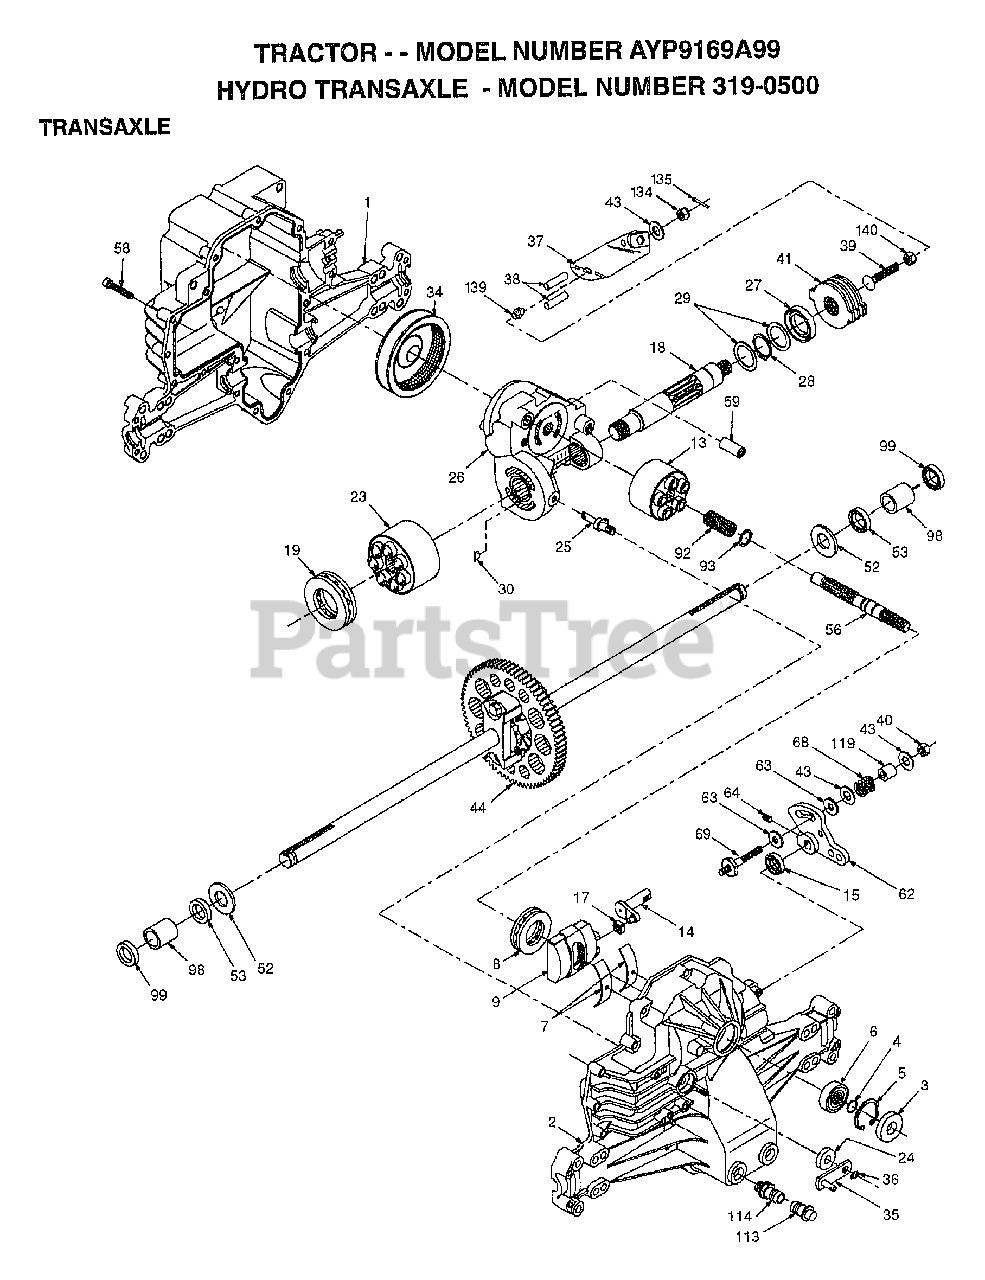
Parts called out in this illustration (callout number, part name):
1	HOUSING.L.44863RM
2	HOUSING.UPR.70122
3	SEAL.9008000-0128
4	RING.RET.2003016.
5	RING.RET.2003052.
6	BEARING.(50552)42X68X16
7	CRADLE- 2003023.
8	BEARING.THU.50551
9	SWASHPLT.2003087.
13	BLOCK.CLYN.70079.
14	ARM.TRUN.2003005.
15	SEAL.9008000-0126
17	GUIDE.2000015.
18	SHAFT.MOTOR.50449
19	BEARING.THU.50552
23	BLOCK.CYLIN.70082
24	SEAL.LIP.45074
25	ACTUATOR.2003555
26	KIT.CEN.SEC.70250
27	SEAL.LIP.45075
28	RING RETAIN 50007
29	WASHER.44872
30	PLATE.BYP.2003554
34	ELEMENT.OIL.44964
35	ARM.BYPASS.50270
36	RING.RETAIN.44870
37	ARM.ACTUAT.23710
38	PIN.ACTUAT.44891
39	BOLT.50316
40	NUT.LOCK.HX.50317
41	KIT.BRAKE.70135
43	WASHER HYD 44130
44	DIFFERNTIAL.70126
52	WASHER.HYD.44875
53	SEAL.HYDRO.45076
56	SHAFT.INPUT.50005
58	BOLT.1/4-20.44876
59	PIN.HYDRO.50002
62	ARM.CONTROL.50254
63	PUCK.DAMPER.50281
64	SCREW.SET.50018.
68	SPRING.HYD.50277
69	STUD.5/16-24.DANA
92	SPRING.2003014.
93	WASHER.2003017
98	BEARING.SLV.50137
99	SEAL.WIPER.50941
113	CAP.VENT.70109
114	O-RING.ASM.70110
119	SPACER.HYD.50278
134	NUT.CAS.HYD.44142
135	PIN.COT.HYD.44101
139	SPRING.COMP.50431
140	NUT.HEX.50269
